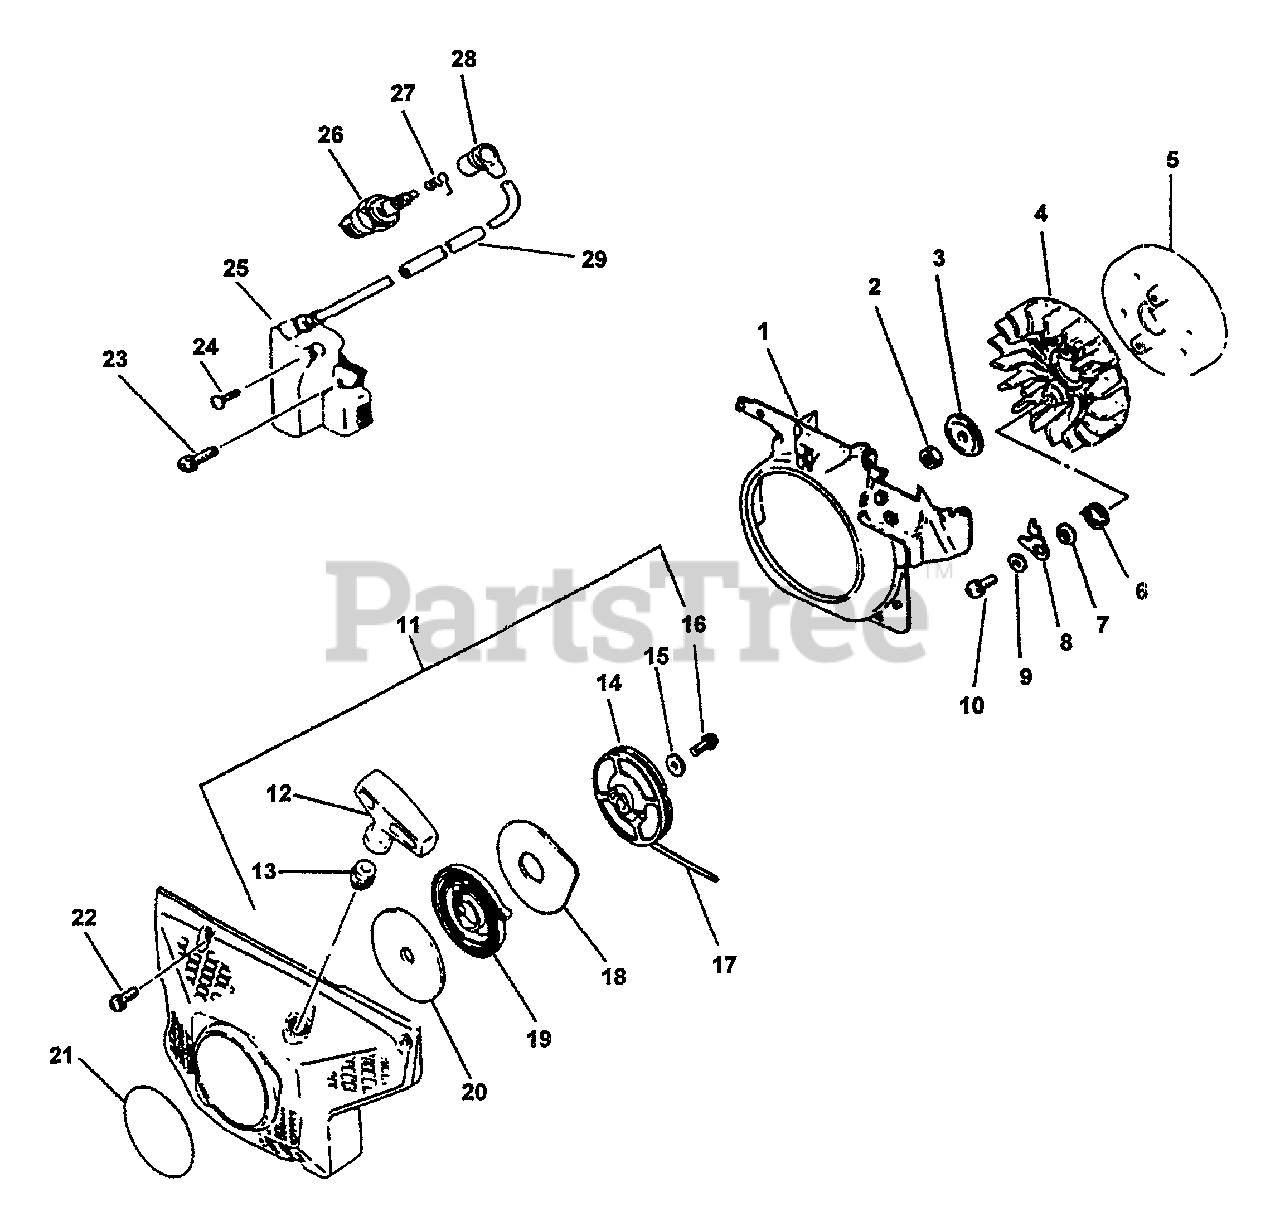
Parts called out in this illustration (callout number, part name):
1	SHIELD, FAN
3	WASHER 8.2×31×0.8
5	FLYWHEEL
6	SPRING, RETURN
7	SPACER, PAWL
8	PAWL, STARTER
9	WASHER 5.5×12×0.8
10	BOLT 5×14
11	STARTER ASSY
12	GRIP, STARTER
13	GUIDE, ROPE
14	REEL, ROPE
15	WASHER 5.5×12×0.8
16	BOLT 5×14
17	ROPE, STARTER 4.0×950
18	PLATE, STARTER
19	SPRING, RECOIL
20	PLATE, STARTER
21	LABEL - ECHO
22	SCREW 5×20
23	BOLT 4×20
24	SCREW 4×8
25	COIL, IGNITION
26	SPARK PLUG - BPM7A
27	TERMINAL, SPARK PLUG
28	CAP, SPARK PLUG
29	TUBE
